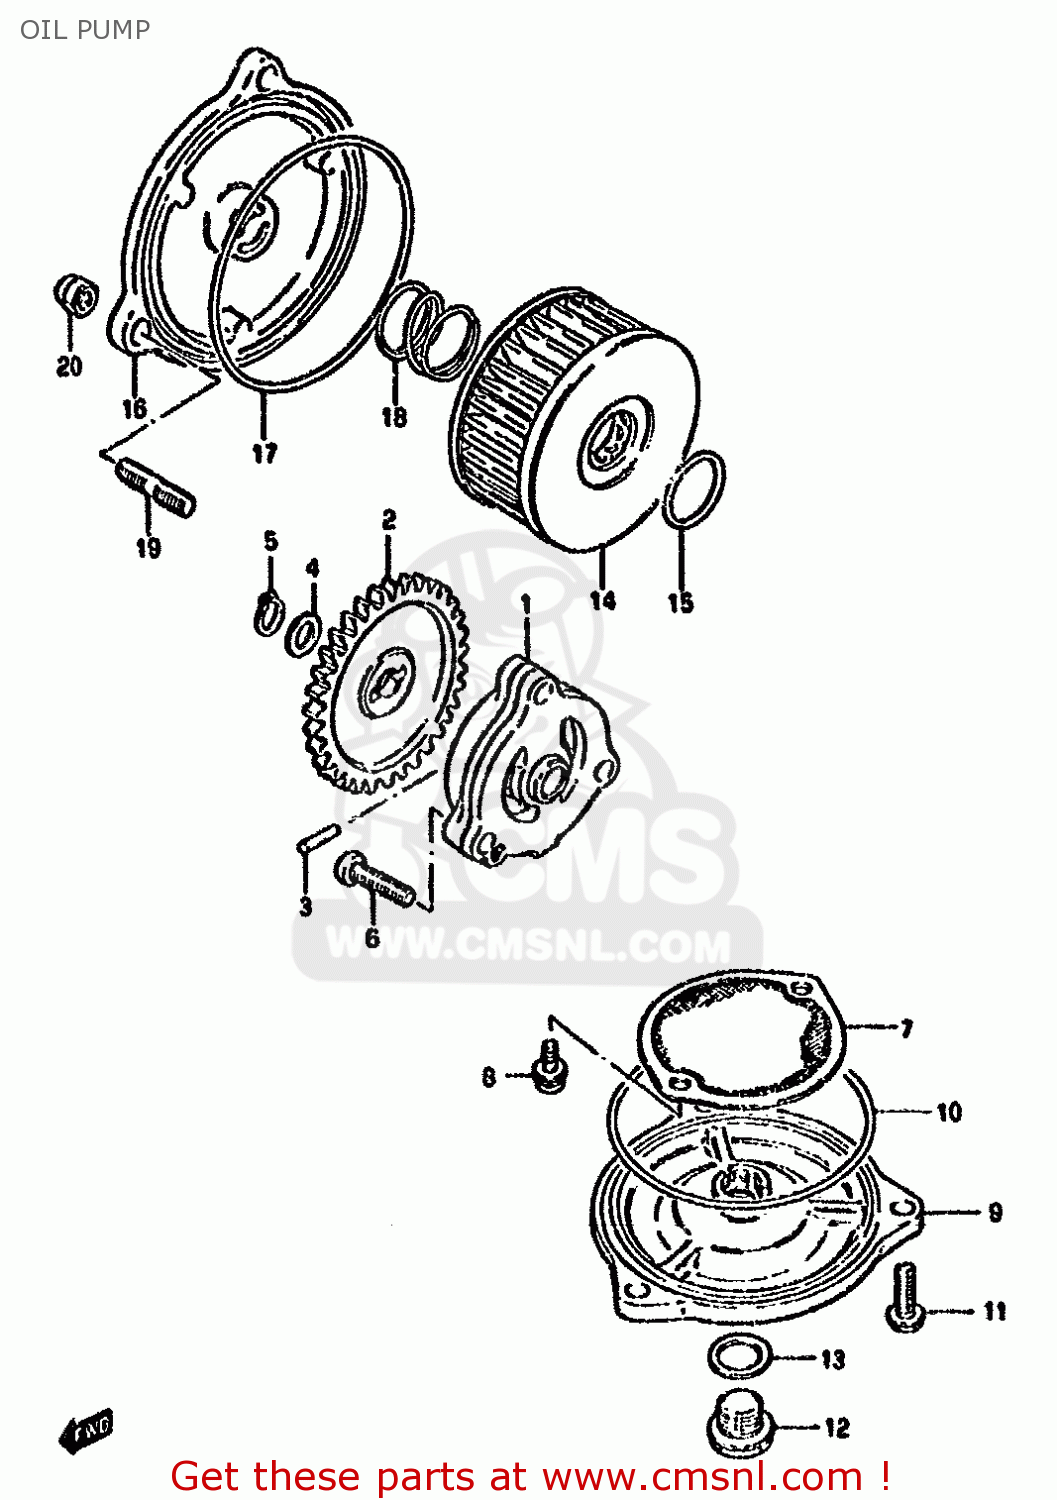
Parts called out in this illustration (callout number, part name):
1	PUMP ASSY,ENGINE OIL
2	GEAR,OIL PUMP DRIVEN(NT:33)
3	PIN(4X15.8)
4	SHIM
5	CIRCLIP,10MM
6	SCREW
7	STRAINER,ENGINE OIL
8	SCREW
9	CAP,OIL STRAINER
10	O RING(D:2.4,ID:85)
11	BOLT
12	PLUG
13	GASKET(14X19.2X2) (NAS)
14	FILTER ASSY,ENGINE OIL
15	O RING(D:2.4,ID:15.8)
16	CAP,OIL FILTER
17	O RING(D:2.4,ID:73)
18	SPRING
19	STUD 6X12
20	NUT
